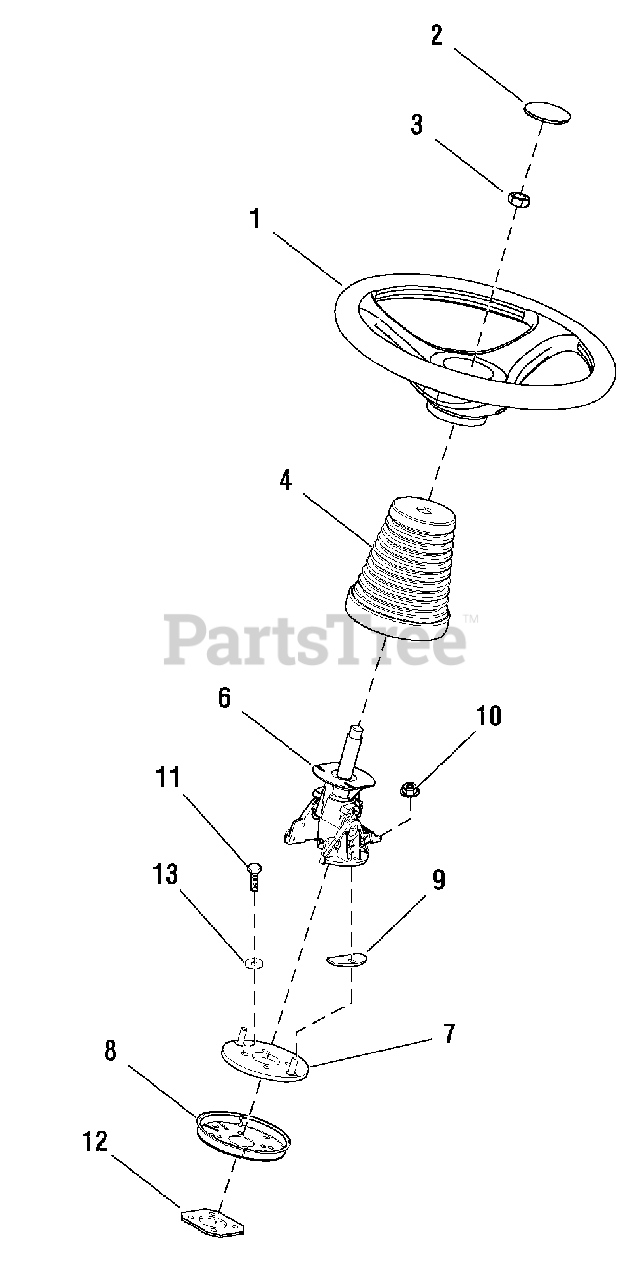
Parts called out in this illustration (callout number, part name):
1	STEERING WHEEL
2	CAP, Steering Wheel
3	NUT, Hex, 5/8-16
4	BELLOWS
6	TILT STEERING
7	PLATE, Steering
8	MOUNT PLATE
9	SPACER, Flat
10	NUT, Hex Keps, 5/16-18
11	CAPSCREW, M6-1x30
12	MOUNT PLATE
13	WASHER, Lock
